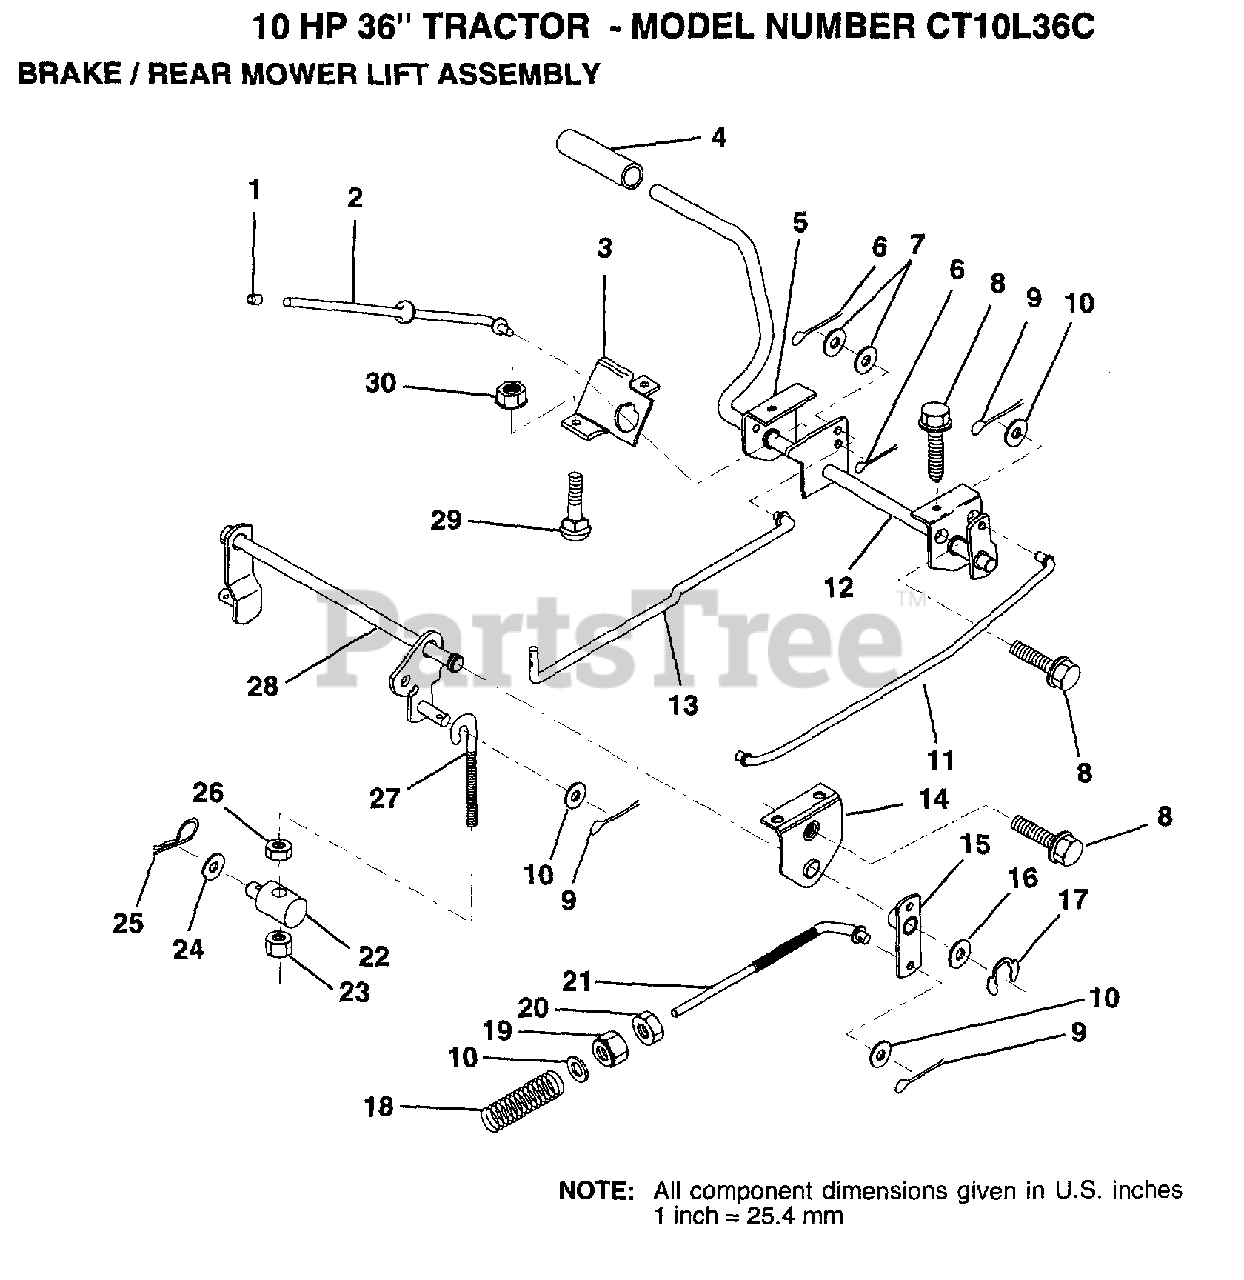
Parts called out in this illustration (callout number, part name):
1	PLUNGER CAP T
2	"ROD,PARK BRAKE"
3	"BRKT,PARK BRAKE"
4	FOOT PEDAL COVER
5	"BRKT,CLU PEDAL LH"
7	WASHER
8	SCREW LT
9	COTTER PIN
10	WASHER
11	"ROD,FRT BRAKE"
12	PEDAL ASM CL/BK36
13	"ROD,CLUTCH"
14	"BRKT,LIFT SHAFT"
15	BRAKE PIVOT ARM
16	WASHER T
17	KLIP RING
18	SPRING ROD LT
19	NUT
20	NUT
23	NUT
24	WASHER
25	SPRING.RETAINER
26	LOCKNUT
27	"LINK, MOWER REAR"
28	LIFT ASM MOW REAR
